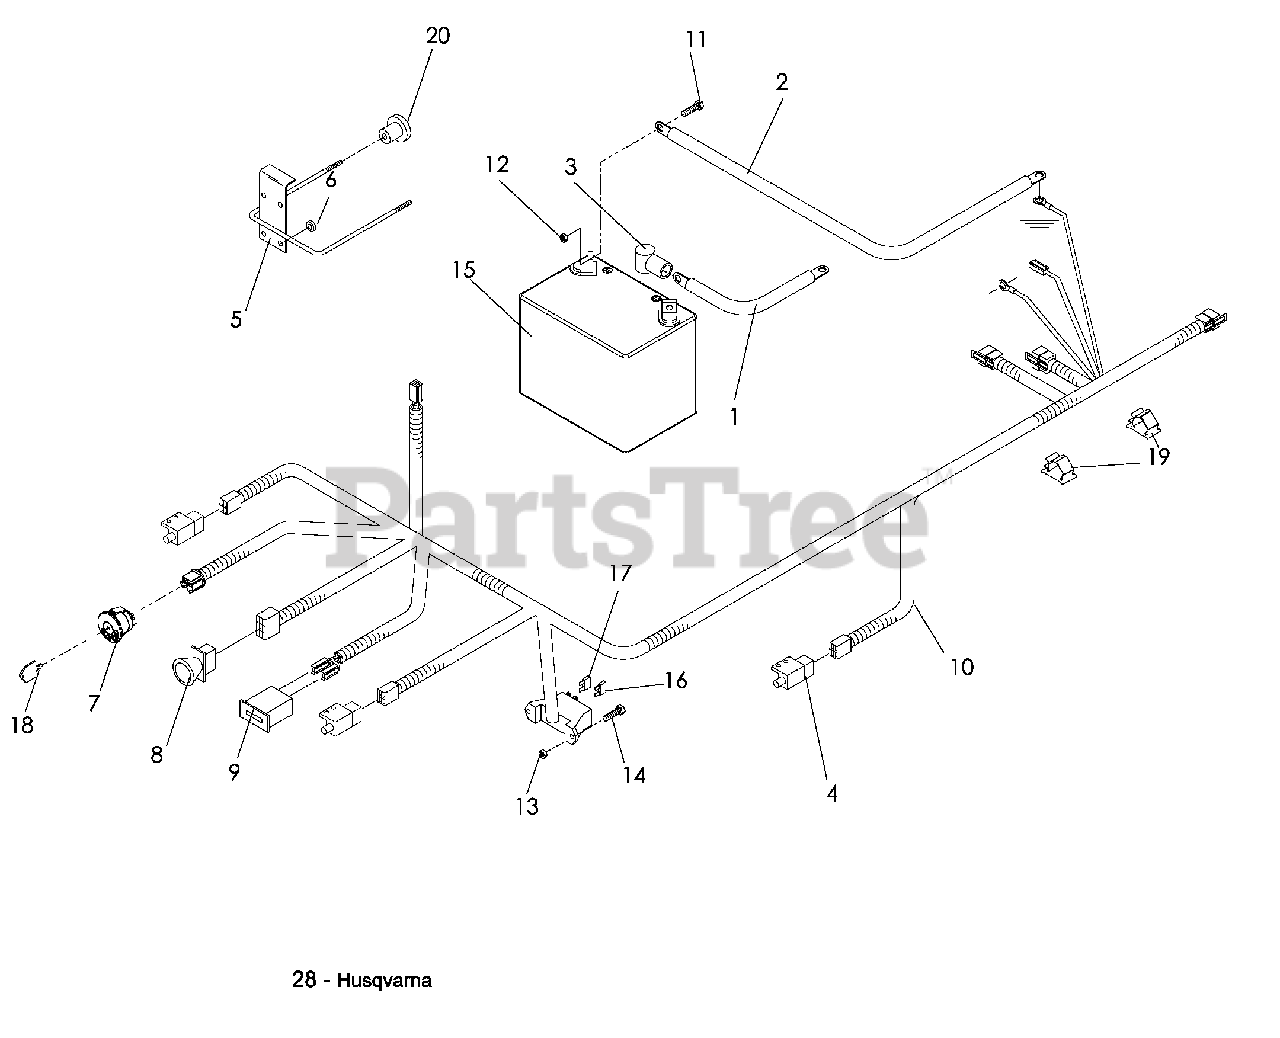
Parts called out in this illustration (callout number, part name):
1	CABLE, POSITIVE
2	CABLE, NEGATIVE
4	SWITCH, INTERLOCK
5	BATTERY HOLD DOWN
7	SWITCH, IGNITION
8	SWITCH, PTO
9	METER, HOUR
10	FRAME HARNESS
11	HCS 5/16-18 x ¾
12	NUT 5/16-18 HEX NYLOC
13	NUT 10-24, NYLOC
14	SCREW 10-24 x 7/8
15	BATTERY, DRY
16	FUSE, 7.5 AMP, 32V, ATO
17	FUSE, 20 AMP, 32 V, ATO
18	KEY, PADDED
19	CLIP, PUSH MOUNT
